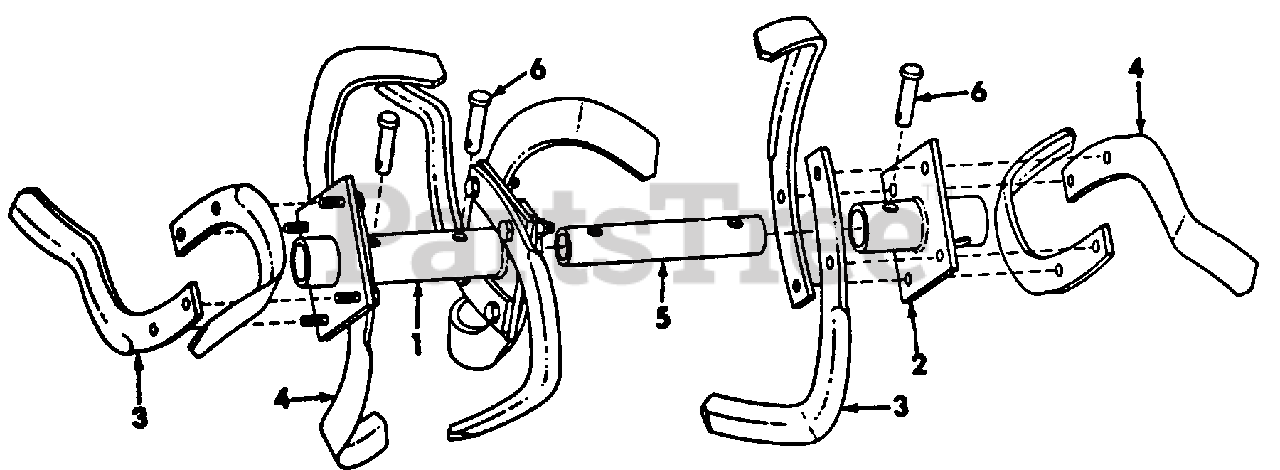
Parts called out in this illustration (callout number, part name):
1	Mounting, Tine - Long
2	Mounting, Tine -Short -Used w/extension
3	Tine, LH -12 used w/Extension
4	Tine, RH -12 used w/Extension
5	Shaft, Extension -2 Used w/Extension
6	Pin, Shear -6 used w/Extension
